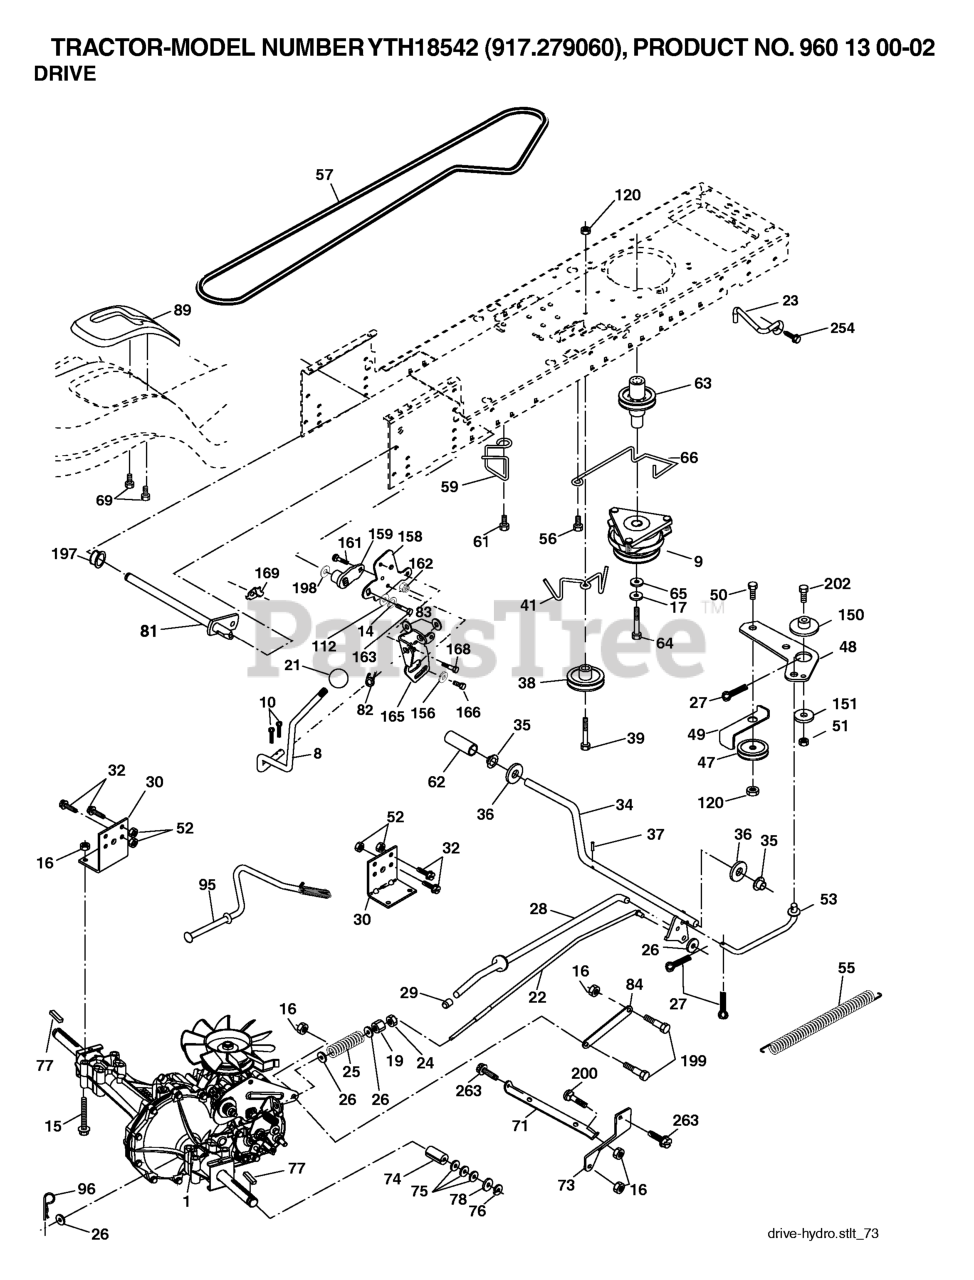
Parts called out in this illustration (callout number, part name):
8	ROD.SHIFT.FENDER.ADJ.STLT
9	RB.CLUTCH.OGURA.4.4.PD
10	PIN COTTER
14	LOCKWASHER
15	BOLT HEX 5/16-18 GR 5
16	NUT.71038.31-18.HEX.NYLOCK
19	NUT
21	KNOB.DELUXE.(PISTOL.GRIP).BLAC
22	ROD BRAKE HYDRO
23	BRACKET, ANTI-ROTATION
24	NUT
25	SPRING ROD LT
26	WASHER
27	COTTER PIN
28	ROD, PARKING BRAKE
29	PLUNGER CAP
30	BRKT, TRNSXLE MNT 20"
32	BOLT
34	SHAFT, FOOT PEDAL
35	BEARING.NYLON
37	DRIVE PIN
38	PULLEY IDLER COMPOSITE
41	KEEPER, BELT IDLER
47	IDLER PULLEY
48	BELLCRANK, CLUTCH
49	RETAIN BELT
50	BOLT.3/8-16X1.50
52	LOCKNUT
53	LINK, CLUTCH LT
55	SPRING, RETURN LT
56	SCREW.3/8-16
57	DRIVE BELT, LTH & YTH TRACTORS
59	KEEPER, BELT CENTER
61	SCREW 3/8-16X.875
62	PEDAL COVER T
63	PULLEY- ENGINE
64	BOLT HEX 7/16-20X4-1/4"
65	LOCKWASHER
66	KEEPER BELT ENGINE
69	SCREW.HI-LO.CONSOLE
71	STRAP TORQUE LH HYDRO
73	STRAP TORQUE RH HYDRO
74	SPACER AXLE
77	SQUARE KEY
81	SHAFT ASM CROSS TAPERED
82	SHIFT SPRING
83	WASHER
84	LINK TRANSAXLE
89	CONSOLE, SHIFT, STL, AUTO GREY
95	CONTROL ASM. BYPASS HYDRO
96	RETAINER M
120	NUT LOCK FLG 3/8-16 UNC
150	SPACER, RETAINER
151	WASHER 12/32X2X10GA
156	WASHER.SRRTD.5/16
158	BRACKET
159	RB HUB.SHIFT
161	BOLT
162	NUT.CROWNLOCK.1/4
165	RP BRACKET
166	CAPSCREW.HXHD.FLG.5/16-18X.625
168	BOLT.SHOULDER.5/16-18X
169	PLATE.FASTENING.CROSS.SHAFT
197	NYLINER SNAP 5/8" ID
198	WASHER.NYL.7/8IDX.105"HYD CR
199	BOLT SHOULDER 5/16-18 UNC
254	SCREW 3/8-16X1
263	SCREW, 3/8-16X3/4
